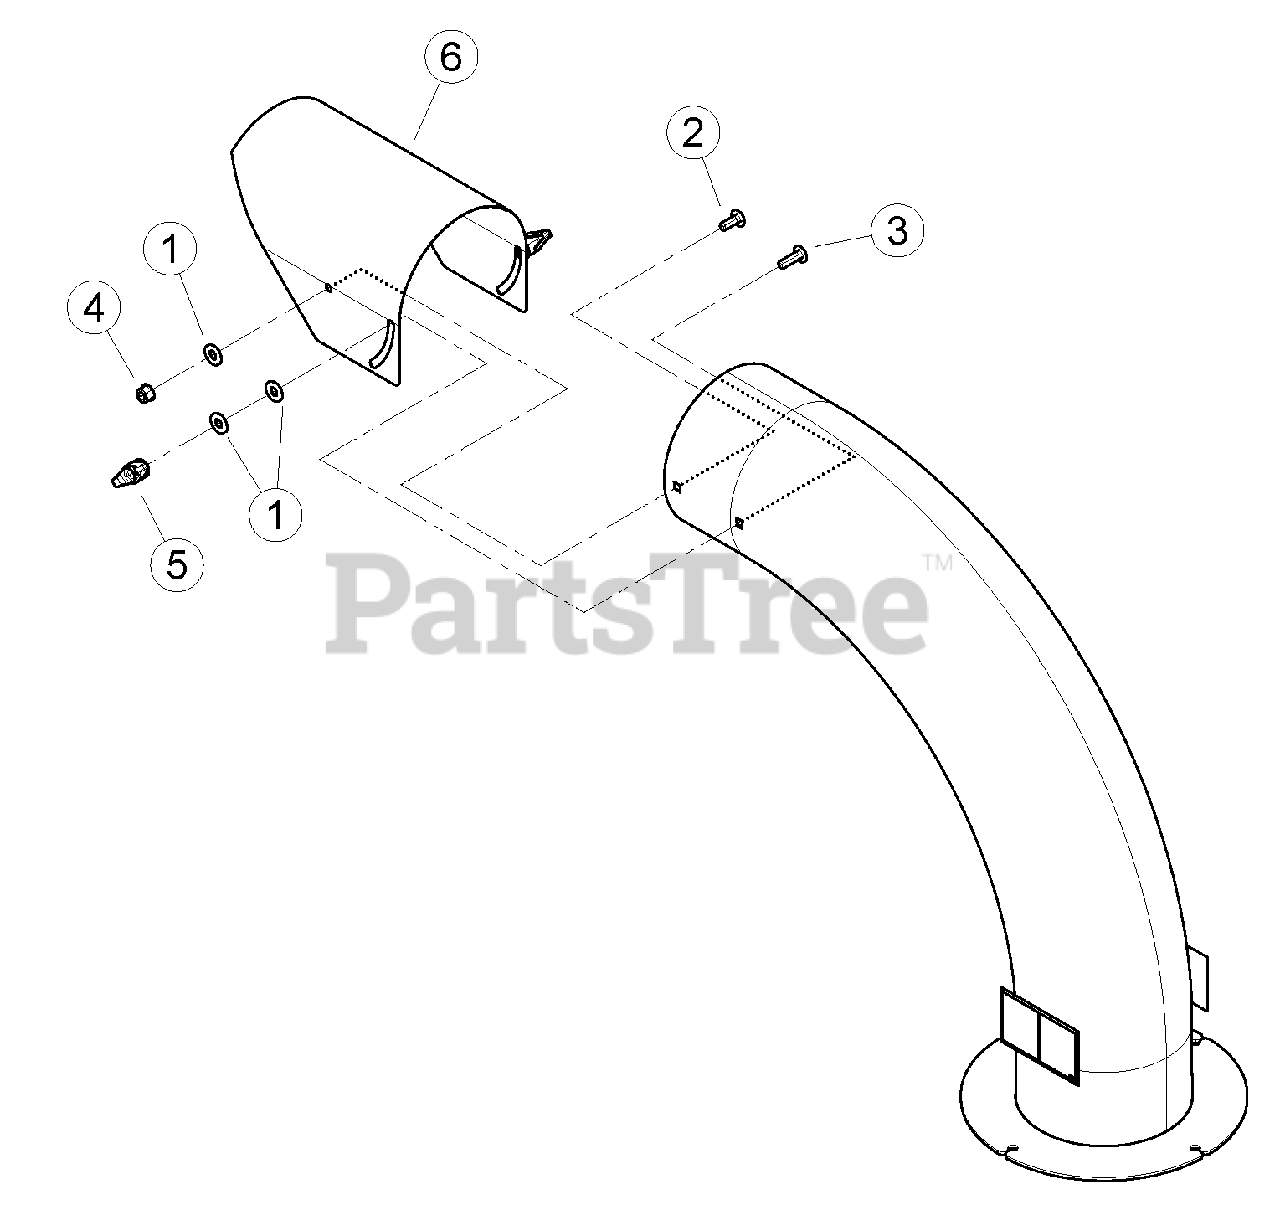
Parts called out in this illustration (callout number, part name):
1	WASHER, 3/8 FLAT
2	BOLT, 3/8-16 X 1 GR5 CRG
3	BOLT, 3/8-16 X 1-1/4 GR5 CRG
4	NUT, 3/8-16 NYLOCK FLANGE
5	KNOB, 3/8-16 UNC FEMALE TEE
6	CAP, 8 INCH DISCHARGE CHUTE
